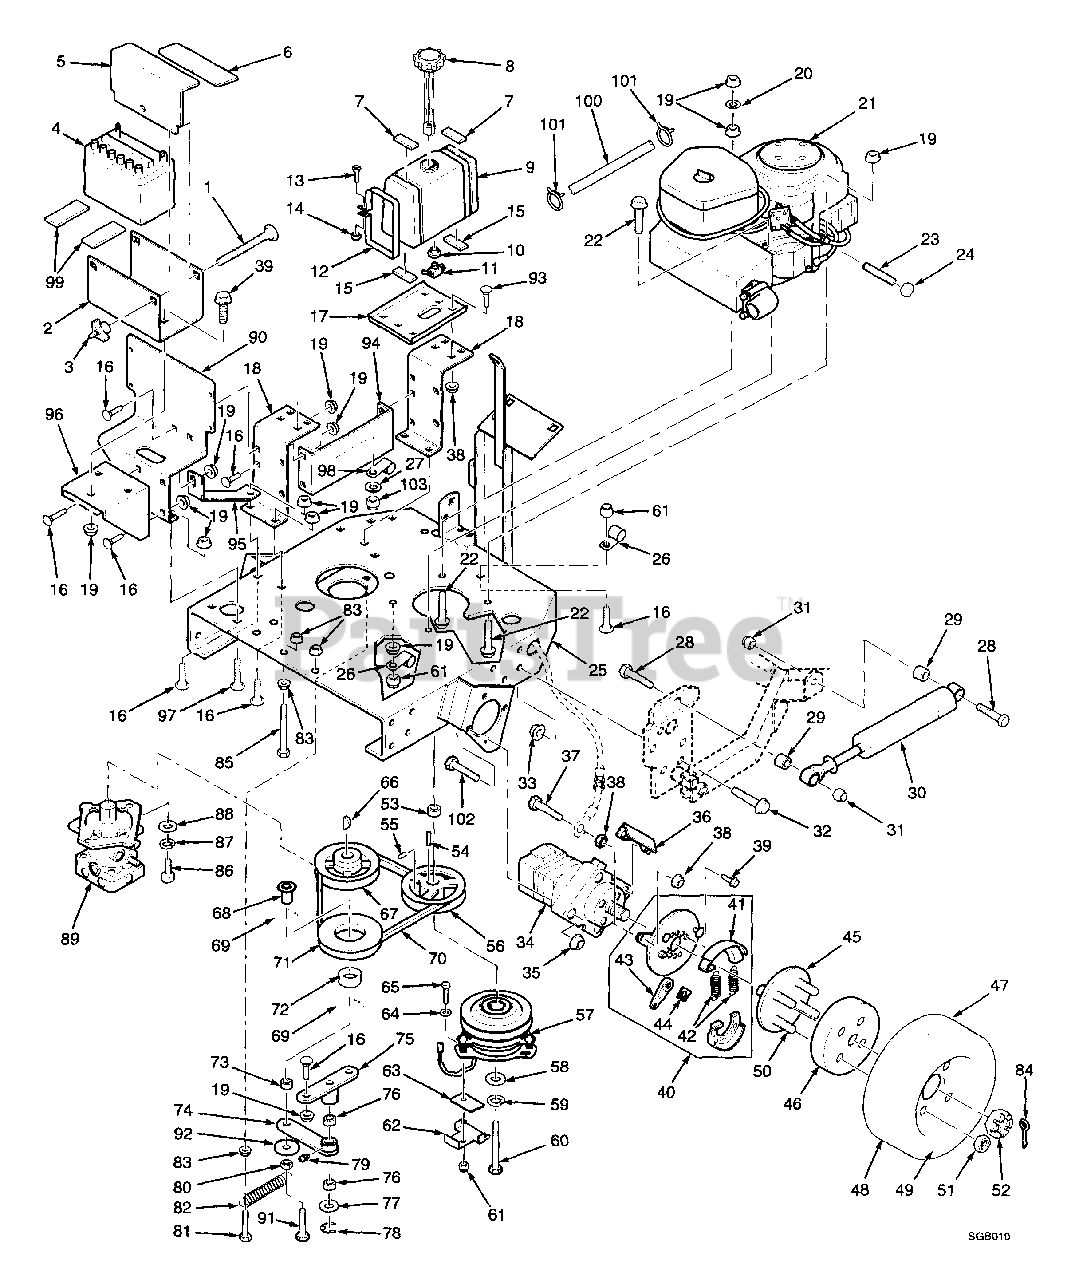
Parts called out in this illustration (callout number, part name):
1	Carriage Bolt, 1/4-20 x 6
2	Battery Box
3	Nut, Wing 1/4-20
4	Battery
5	Battery Cover
6	Insulation, Battery Cover
7	Pad, Fuel Tank Strap
8	Cap, Fuel Tank
9	Fuel Tank Assy.
10	Bushing, Fuel Tank Valve
11	Fuel Shut Off Valve
12	Strap, Fuel Tank
13	Phil RDHD Machine Screw 1/4-20 x 2
14	Hex Nut, 1/4-20
15	Pad, Fuel Tank Support
16	Carriage Bolt, 5/16-18 x 3/4
17	Support, Fuel Tank
18	Bracket, Fuel Tank Support
19	Serr. Fl. Hex Nut 5/16-18
20	Lockwasher, 5/16 Int. Tooth
21	Engine, 20 HP Kohler CV
22	Hex Head CPSCR, 5/16-18 x 1 3/4
23	Oil Drain Extension
24	Cap, Oil Drain Plug
25	Engine Deck
26	Wire Loom, .50 I.D.
27	Washer, 1/4 (.312 x .750 x .065)
28	Bolt, Hex Head 1/2-13 x 2
29	Sleeve, Shock Absorber Mount
30	Shock Absorber
31	Hex Locknut, Elastic Stop 1/2-13
32	Serr. Fl. Hex Head CPSCR, 7/16-14 x 1
33	Serr. Fl. Hex Nut, 7/16-14
34	Motor - White
35	Lockwasher, 1/2
36	Anchor, Brake
37	Bolt, Hex Head 1/4-20 x 1-1/4
38	Serr. Fl. Hex Nut, 1/4-20
39	Serr. Fl. Hex Head CPSCR, 5/16-18 x .75
40	Parking Brake Assembly
41	Brake Pads- Pair
42	Springs - Pair
43	Actuating Arm
45	Hub Assembly
46	Brake Drum
47	Rim and Tire Assembly
48	Tire 20 x 10 x 10, 4 Ply
49	Rim Only
50	Bolt, Hub
51	Wheel Nut
52	Castle Nut, 1.0-20 UNEF
53	Spacer, Clutch
54	Key, 1/4 x 1/4 x 1-1/2
55	Hex Socket Set Screw, 5/16-18 x 3/8
56	Pulley, Engine Pump Drive
57	Clutch, Electric
58	Flatwasher, 7/16 (.469 x 1.50 x .25)
59	Lockwasher, 7/16
60	Bolt, Hex Head 7/16-20 x 3
61	Hex Locknut, Elastic Stop 5/16-18
62	Backing Plate, Clutch Stop
63	Rubber Pad, Clutch Stop
64	Flatwasher, 5/16 (.375 x .875 x .083)
65	Bolt, Hex Head 5/16-18 x 1-1/4
66	Key, Woodruff 3/16 x 5/8
67	Pulley, Pump Input
68	Sleeve, Idler
69	Ring, Retaining, 1-9/16 internal
70	Belt, Pump Drive
71	Pulley, Idler-Traction Drive
72	Bearing, Idler Pulley
73	Spacer, Idler
74	Pump Idler Arm
75	Idler Pivot Base
76	Bushing, Oil lube
77	Flatwasher, 3/4
78	Ring, Retaining, 3/4 Ext. "E"
79	Grease Fitting
80	Hex Nut, Jam 3/8-16
81	Bolt, Hex Head 3/8-16 x 3-1/4
82	Spring, Pump Drive Idler
83	Serr. Fl. Hex Nut, 3/8-16
84	Cotter Pin, 5/32 x 1.50
85	Bolt, Hex Head 3/8-16 x 5
86	Socket Head CPSCR, 1/2-13 x 1-1/4
87	Lockwasher, 1/2
88	Flatwasher, 1/2 (.5/6 x .938 x .105)
89	Pump, Sundstrand
90	Bracket, Oil Tank Support
91	Bolt, Hex Head 3/8-16 x 1-3/4
92	Washer 2" OD, 3/8 ID, 16 Ga.
93	Carriage Bolt, 1/4-20 x 3/4
94	Guard, Pulley
95	Gusset, Battery Box
96	Support, Battery Box
97	Carriage Bolt, 5/16-18 x 1"
98	Wire Loom, .75 I.D.
99	Rubber Pad
100	Fuel Hose, 26"
101	Clamp, Fuel Hose
102	Bolt, 1/2-13 x 2.50"
103	Nut, 1/4-20 Elastic Stop
